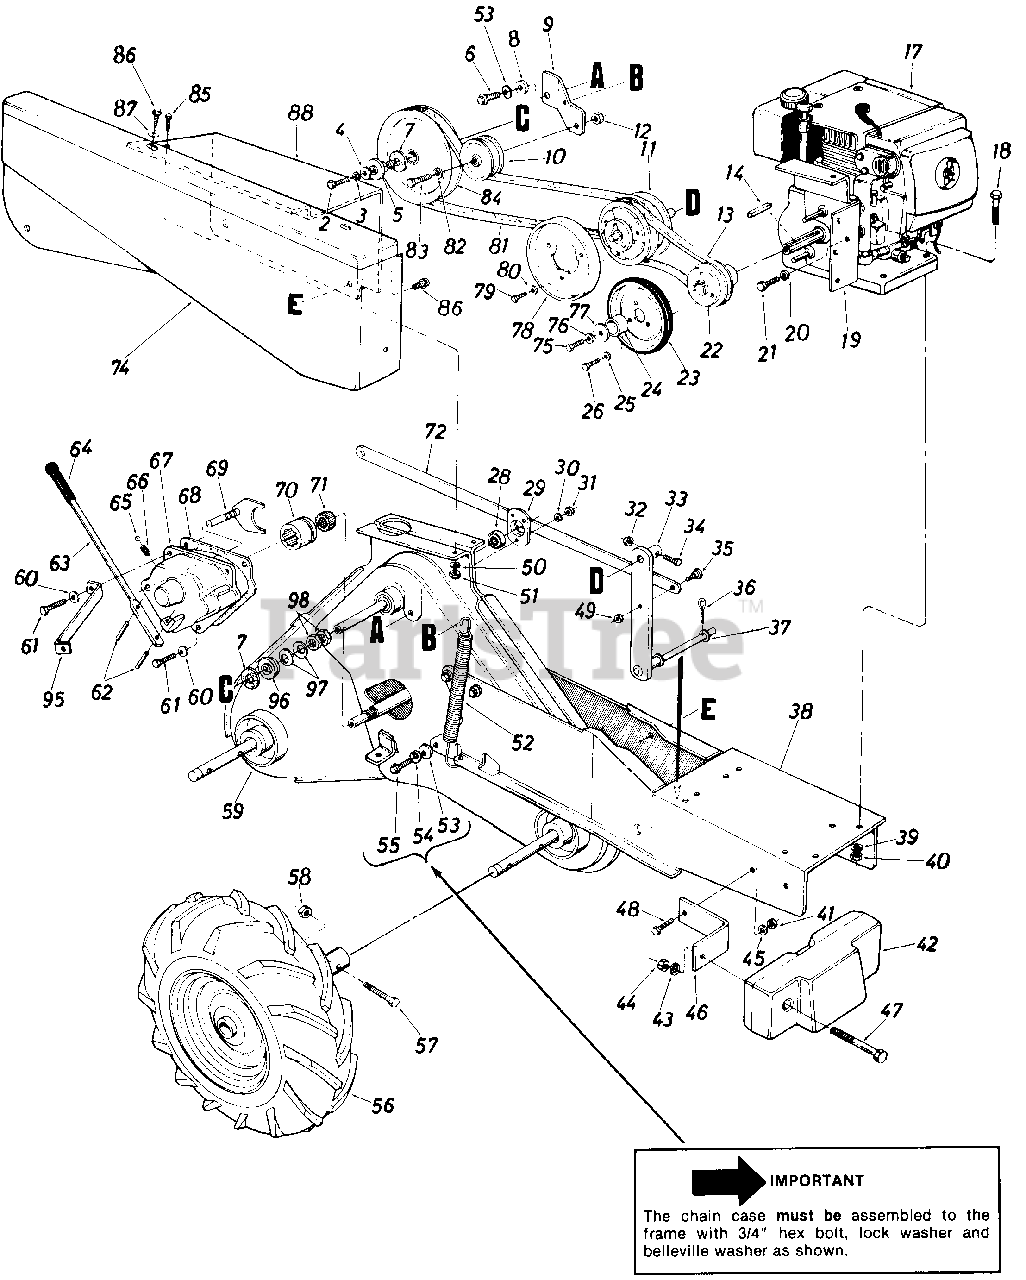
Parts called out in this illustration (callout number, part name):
2	Hex L-Bolt 5/16-24 x 1.5" Lg.
3	L-Wash. 5/16" I.D.
4	Fl-Wash. 5/16" I.D. x 1.125" O.D.
5	Friction Disc Ass'y.
6	Hex Bolt 3/8-24 x 1.25" Lg.
7	Friction Pad
8	Shoulder Spacer
9	Idler Bracket
10	Fl-Idler 2.75" Dia.
11	Variable Speed Ass'y.
12	Hex Ins. L-Nut 3/8-16 Thd.
13	"V"-Belt 5/8" x 27.0" Lg.
14	Sq. Key 1/4" x 2.00" Lg.
18	Hex Bolt 5/16-18 x 1.75" Lg.
19	Belt Cover Support Ass'y.
20	Internal L-Wash. 1/2" I.D.
21	Hex Bolt 1/2-20 x .75" Lg.
22	Engine Pulley Ass'y.
23	Friction Wheel Ass'y.
24	Spacer
25	L-Wash. 5/16" I.D.
26	Hex Bolt 5/16-18 x .50" Lg.
28	Ball Bearing
29	Bearing Housing 1-3/8 O.D.
30	L-Wash. 1/4" I.D.
31	Hex Nut 1/4-28 Thd.
32	Hex Ins. L-Nut 1/4-20 Thd.
33	Variable Speed Brk't. Ass'y.
34	Hex Bolt 1/4-20 x 1.25" Lg.
35	Shld. Bolt 1/2" Dia. x .25" Lg.
36	Cotter Pin 1/8" Dia. x 1.0" Lg.
37	Fl-Wash. .686" I.D. x 1.25" O.D.
38	Frame Ass'y.
39	L-Wash. 5/16" I.D.
40	Hex Nut 5/16-18 Thd.
41	Hex Cent. L-Nut 3/8-24 Thd.
42	Weight
43	Fl-Wash. .50" I.D. x 1.0" O.D.
44	Hex Nut 1/2-13 Thd.
45	L-Wash. 3/8" I.D.
46	Weight Mtg. Brk't.
47	Hex Bolt 1/2-13 x 4.50" Lg.
48	Hex Bolt 3/8-24 x 1.00" Lg.
49	Hex Ins. L-Nut 3/8-16 Thd.
50	L-Wash. 1/4" I.D.
51	Hex Cent. L-Nut 1/4-28 Thd.
52	Spring Idler Bracket
53	Belleville Wash. 3/8 I.D.
54	L-Wash. 3/8 I.D.
55	Hex Self-Tap Scr. 3/8-16 x .75" Lg.
56	Wheel Ass'y. Comp. R.H.
57	Hex Bolt 3/8-24 x 1.25" Lg.
58	Hex Ins. L-Nut 3/8-24 Thd.
59	Chain Case Ass'y. Comp.
60	L-Wash. 5/16" I.D.
61	Hex Tap Tite Scr. 5/16-18 x .75" Lg.
62	Headed Spiral Pin 3/16 x 13/16" Lg.
63	Engagement Lever
65	Ball Detent.250" Dia.
66	Compression Spring
67	Shift Housing R.H.
68	Gasket Shift Housing
69	Sh i ft Yoke Ass'y. R.H.
70	Clutch Dog
71	Clutch Dog Driver
72	Control Brk't.
74	Shroud Belt Cover
75	Hex Bolt 7/16-20 x 2.25" Lg.
76	L-Wash. 7/16" I.D.
77	Fl-Wash. .44 I.D. x 1.38" O.D.
78	Friction Disc
79	Hex Bolt 1/4-28 x .50" Lg.
80	L-Wash. 1/4" I.D.
81	"V"-Belt 5/8" x 51" Lg.
82	L-Wash. 3/8 I.D.
83	Hex Bolt 3/8 x 1.50" Lg.
84	Input Pulley Chain Case
85	Hex Bolt 1/4-28 x .62" Lg.
86	Hex Wash. Hd. Self-Tap Scr.
87	Fl-Wash. 1/4" I.D.
88	Belt Cover Shroud
95	Brace
96	Floating Disc
97	Spring Bell-Wash.
98	Hex Jam Nut 1.0-14
